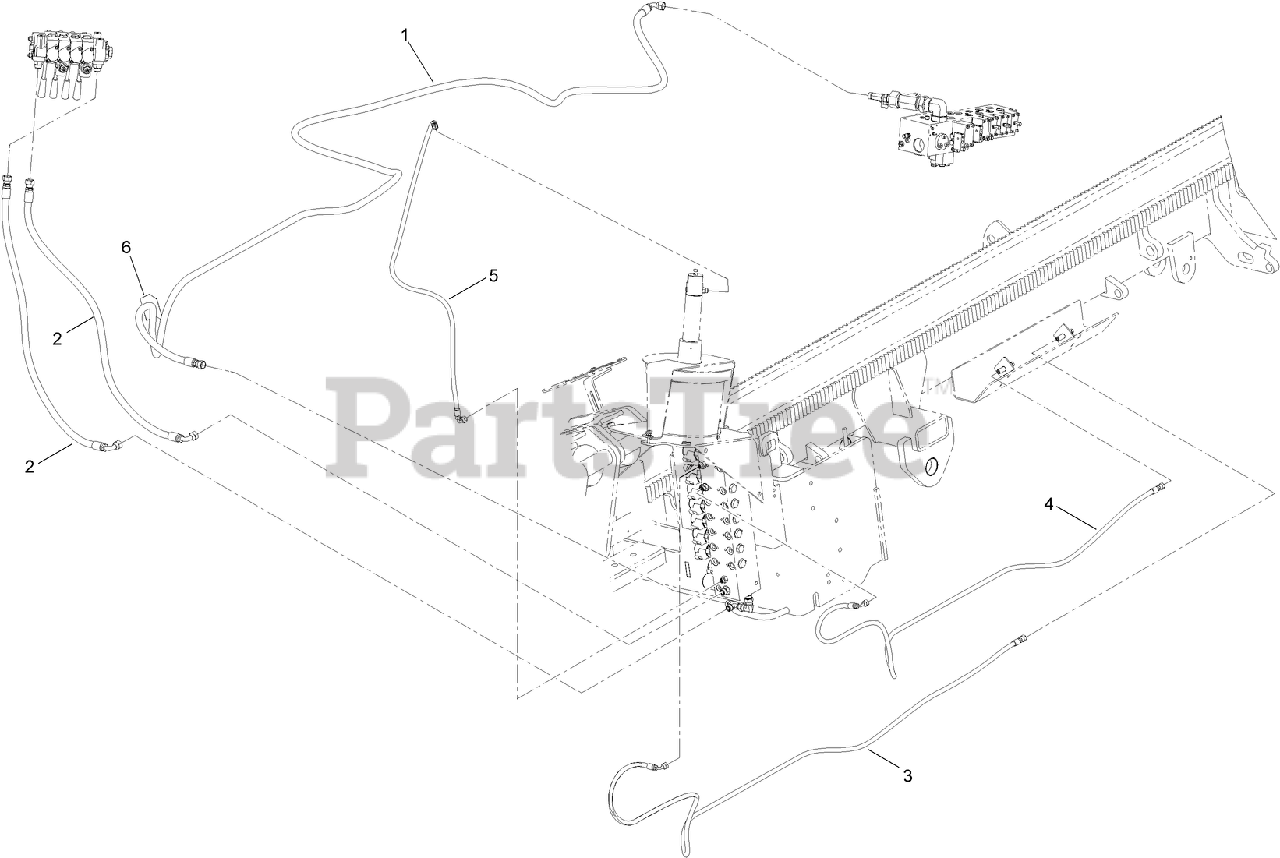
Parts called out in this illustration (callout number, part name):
1	HOSE ASM-HYD
2	HOSE ASM-HYD
3	HOSE ASM-HYD
4	HOSE ASM-HYD
5	HOSE ASM-HYD
6	PROTECTOR-HOSE
